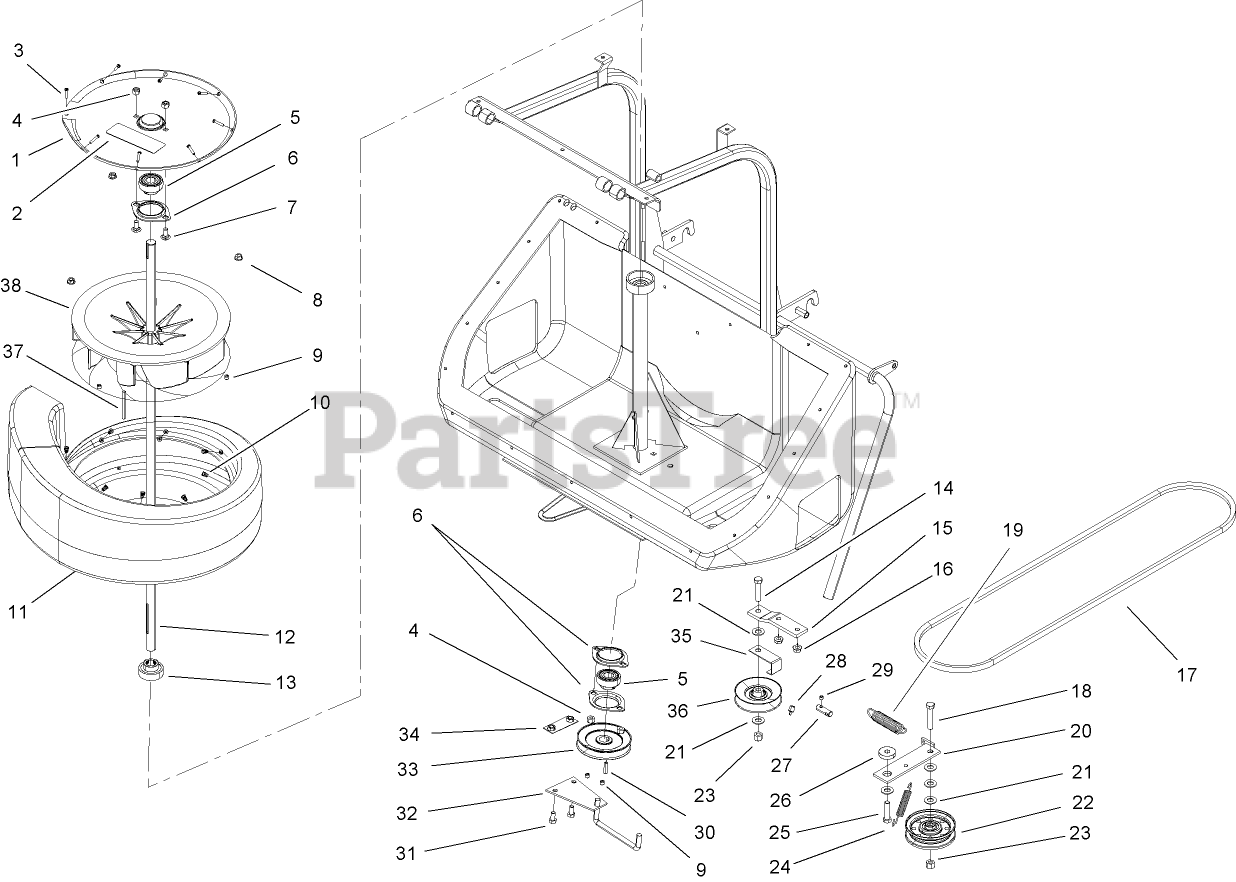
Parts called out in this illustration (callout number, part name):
2	DECAL-HAZARD, ADD WEIGHT
3	SCREW-PPH
4	NUT-LOCK, NI
5	BEARING
6	FLANGE
7	BOLT-CARR
8	NUT-HF
9	SCREW-SET, HSH
10	NUT-INSERT
12	SHAFT
13	BEARING
14	SCREW-HH
16	NUT-HF
17	BELT-V
18	SCREW-HH
19	SPRING-EXTENSION
20	ARM-IDLER
21	WASHER-FLAT
22	IDLER-FLAT
23	NUT-LOCK, NI
24	SPRING-EXTENSION
25	SCREW-HH
26	WASHER-FLANGE
27	END-CABLE
28	GROMMET-CABLE
29	SCREW-SET, HSH
31	SCREW-HH
32	GUIDE-BELT
33	PULLEY-V
34	PLATE-MOUNTING
35	GUIDE-BELT
36	PULLEY-V
